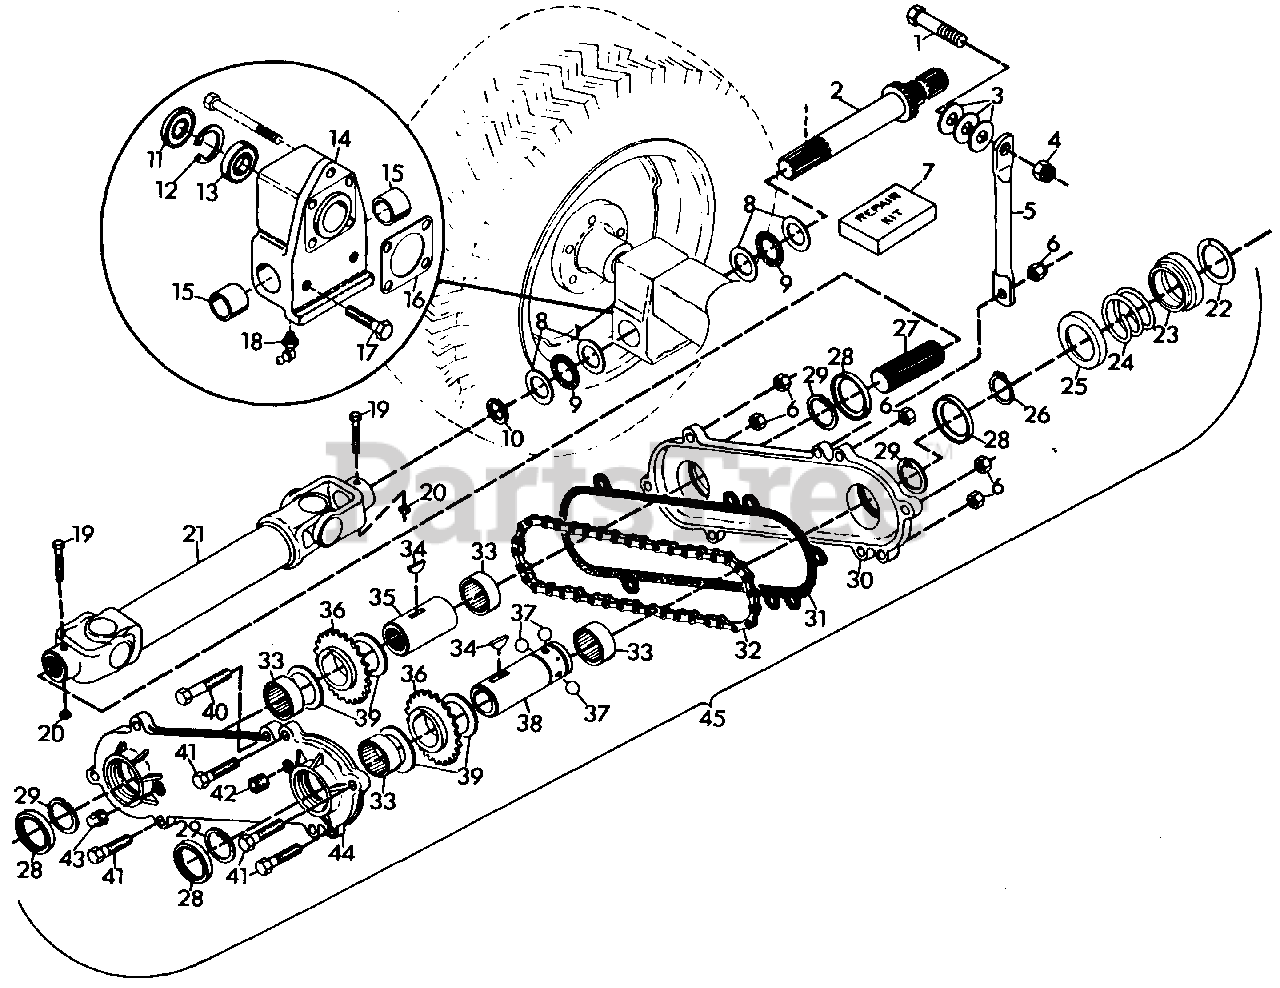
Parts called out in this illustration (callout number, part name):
1	BOLT, HEX 1/2-13X2.00
2	SHAFT
3	WASHER, FLAT .500X1.250X.083
4	NUT, LOCK 1/2-13
5	BRACKET, REAR PTO
6	NUT, LOCK 3/8-16
7	KIT, REPAIR U-JOINT
8	RACE, BEARING THRUST
9	BEARING, NEEDLE THRUST
10	RING, RETAINING 1.00 SHAFT
11	SEAL, OIL AXLE
12	RING, RETAINING
13	BEARING, BALL 1.250X2.250X.500
14	ASSEMBLY, AXLE RETAINER
15	BEARING, BRONZE 1.002X1.378X1.000
16	GASKET
17	BOLT, HEX 1/2-13X1.00
18	FITTING, LUBE 90 DEGREE
19	BOLT, HEX 1/4-20X2.00
20	NUT, LOCK 1/4-20
21	SHAFT, DRIVE(REAR)
22	RING, SNAP
23	COLLAR
24	SPRING
25	RETAINER, INNER
26	RING, RETAINING
27	SHAFT
28	SEAL, OIL 1.500X2.125X.312
29	RING, RETAINING
30	HOUSING, REAR
31	GASKET
32	CHAIN, ROLLER
33	BEARING, NEEDLE 1.500X1.875X.50
34	KEY, WOODRUFF .187X.625 HARD #61
35	SHAFT
36	SPROCKET, 5/8 PITCH 14 TEETH
37	BALL, 3/8
38	SHAFT
39	BEARING, THRUST RACE
40	BOLT, HEX 3/8-16X2.50
41	BOLT, HEX 3/8-16X2.00
42	PLUG, VENTED
43	PLUG, PIPE .50 SQ HD STEEL
44	HOUSING, FRONT
45	ASSEMBLY, DRIVE CHAIN
